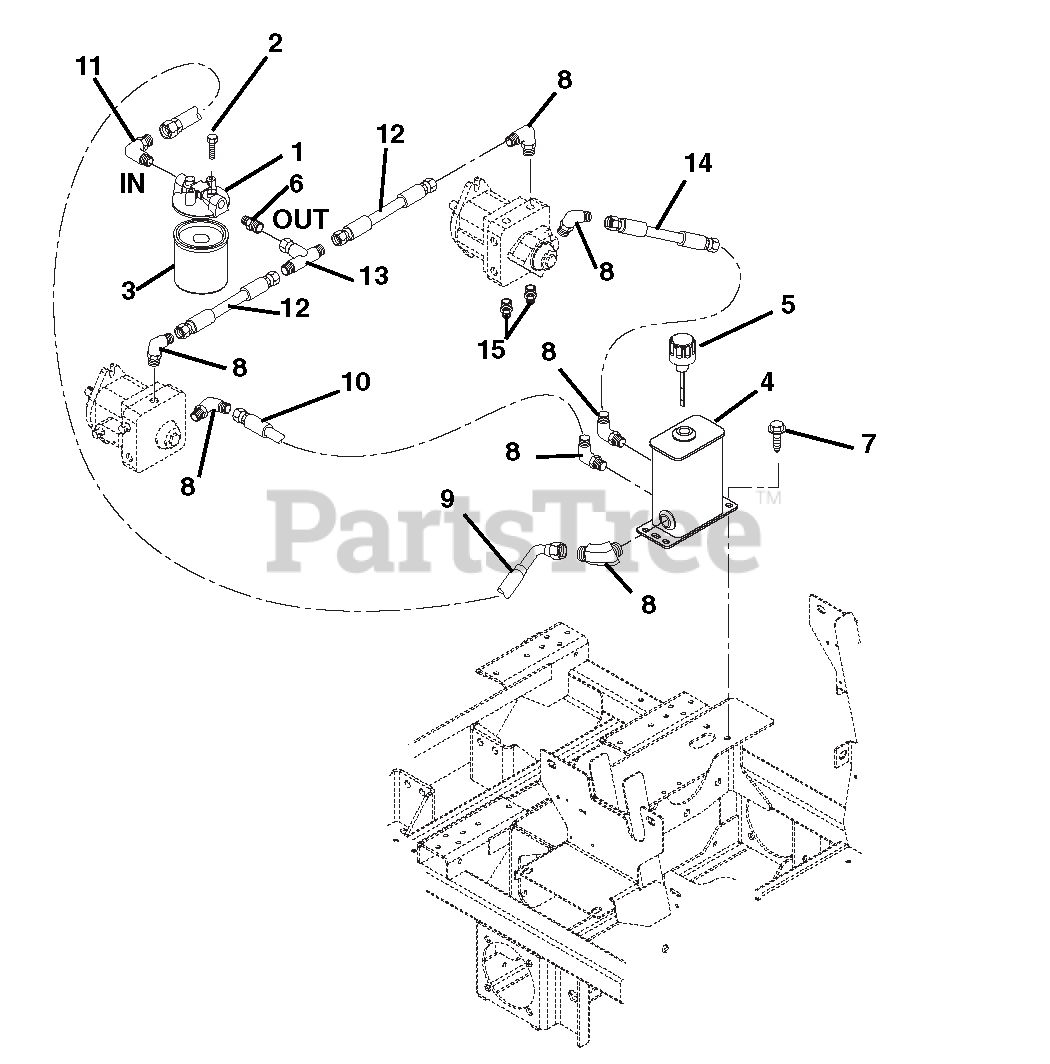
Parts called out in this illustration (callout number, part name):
1	HEAD, FILTER
2	BLT-HEX .25-20X.50 GR5 EPOXY
3	FILTER,OIL-W/BYPASS
4	WMT,FORMED HYD.TANK-3 PORT
5	BREATHER, DIPSTICK
6	ADPTR,FACE SEAL 8X8 1/2 O-RING
7	@SCR-TAP .38-16X.75 HWH TR YWZ
8	FTG. HYD. 90 EL M8F-M8O
9	HOSE, HYD. .50-19-0K F8F0-F8F9
10	HOSE,HYD..50-10-0K FO8J0-FO8JO
11	FTG. HYD. 90 EL M8F-M8O
12	HOSE,HYD. .50-5-0K FO8J0-FO8J0
13	FTG.HYD TEE M8O-F8O-F8O
14	HOSE,HYD..50-16-0K FO8J0-FO8J0
15	FITTING, HYD (4 F5OLO)
